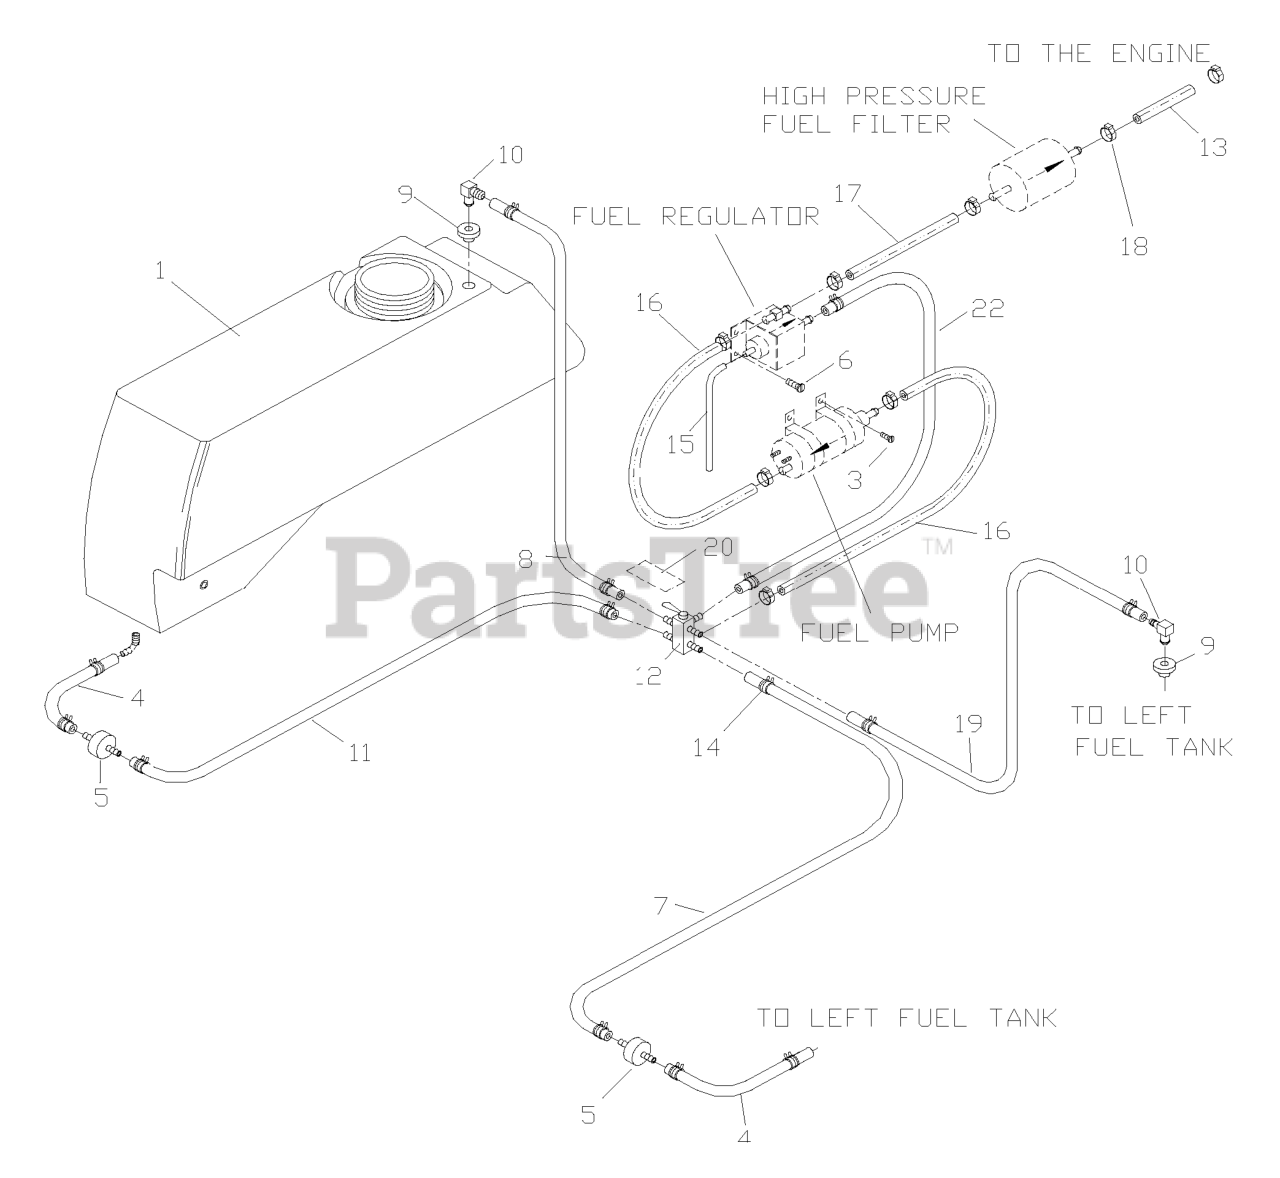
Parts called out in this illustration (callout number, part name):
1	FUEL TANK DIESEL RT
3	SCREW #10 X 1/2 SELF TAPPING
4	GAS LINE 3 1/2"
5	FUEL FILTER
6	HEX CAP SCREW 1/4
7	FUEL LINE 29.5"
8	FUEL LINE 18"
9	RUBBER GROMMET
11	FUEL LINE 24"
12	FUEL VALVE
13	HOSE, FUEL INJ .31 ID X 30"
14	HOSE CLAMP
16	HOSE, FUEL INJ .31 ID X 27"
17	EFI HOSE - 18"
19	FUEL LINE 34"
20	FUEL VALVE DECAL
22	FUEL LINE 29.5"
